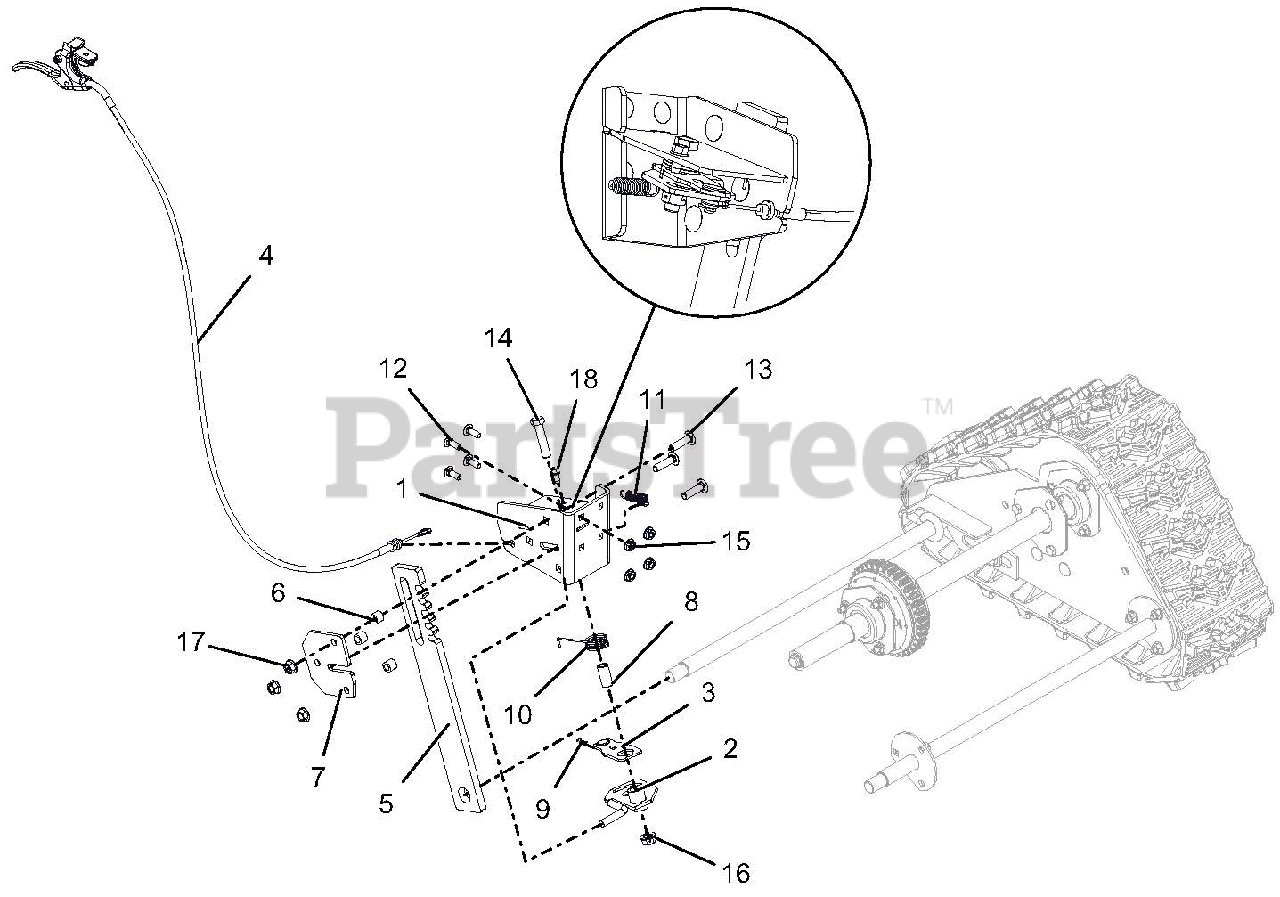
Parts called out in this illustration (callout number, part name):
1	BRACKET, HEIGHT ADJUSTER-PRO
2	LOCK, HEIGHT ADJUSTER
3	ARM, OVERTRAVEL
4	CABLE, TRACK REMOTE
5	STOP, HEIGHT ADJUSTER-PRO
6	SPACER .50 X .32 X .42
7	PLATE, HEIGHT ADJUSTER
8	BSHG-SLV .385X.500X1.045
9	PIN-HAIR INT .06X.18X.77
10	SG-TORS .067X.88
11	SPRING-EXT .047 X .438 X 1.85
12	@BLT-RDHDSQNK .25-20X.75 G5YZ
13	@BLT-RHDSHSQNK.31-18X1.25 G5YZ
14	@BLT-HEX .38-16X1.75 GR5 YWZC
15	@NUT-LK-CTR-FLG .25-20 YWZC
16	NUT-LK-CTR-FLG .38-16 YWZC
17	@NUT-LK-TOP-FLG .31-18 YWZC
18	SCR-TAP .25-20X.50 HWH TR YWZ
